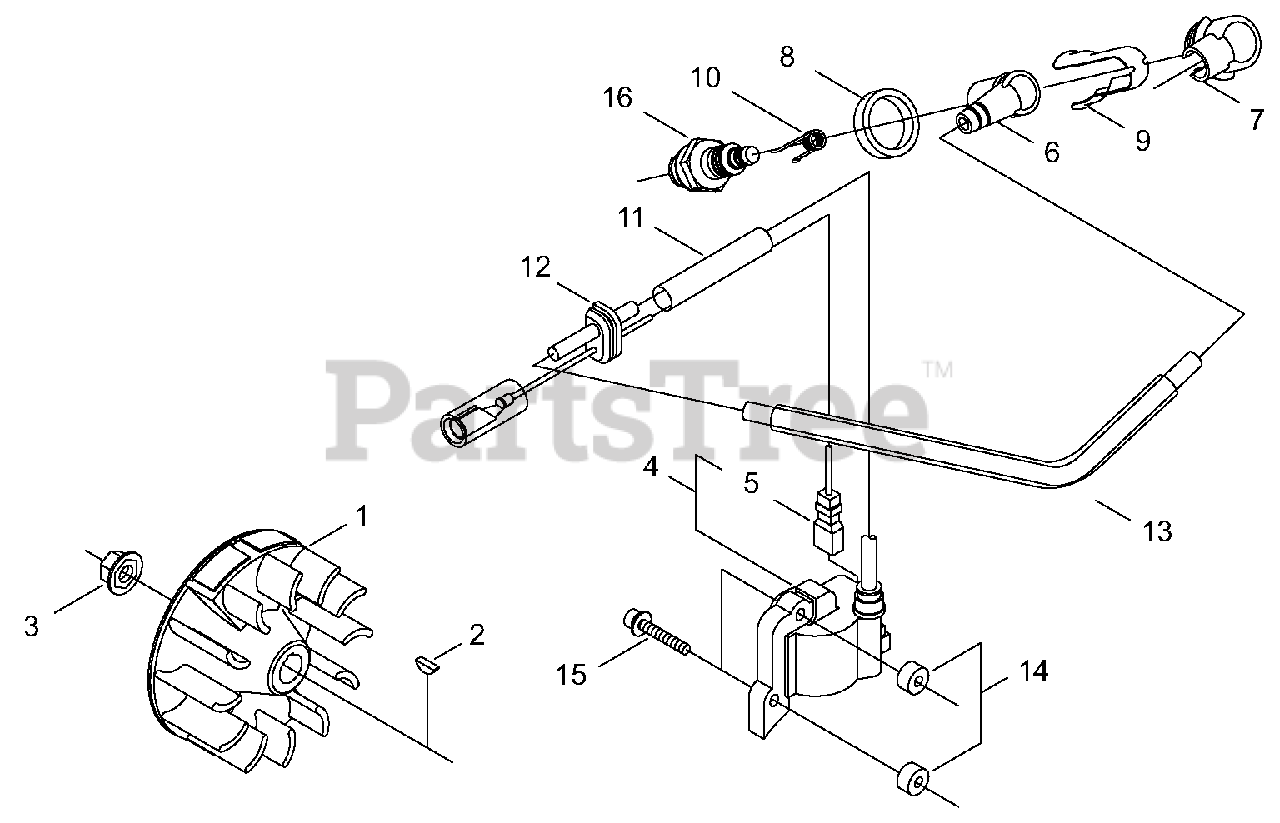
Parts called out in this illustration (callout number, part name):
1	FLYWHEEL
2	KEY - 3X10
3	NUT - 8
4	IGNITION COIL ASSY
5	WIRE
6	CAP, SPARK PLUG
7	COVER, CAP
8	SEAL, DUST
9	SHIELD
10	TERMINAL, SPARK PLUG CAP
11	TUBE, INSULATOR
12	GROMMET
13	TUBE
14	INSULATOR
15	SCREW - 4X26
16	SPARK PLUG -- BMR-6A
